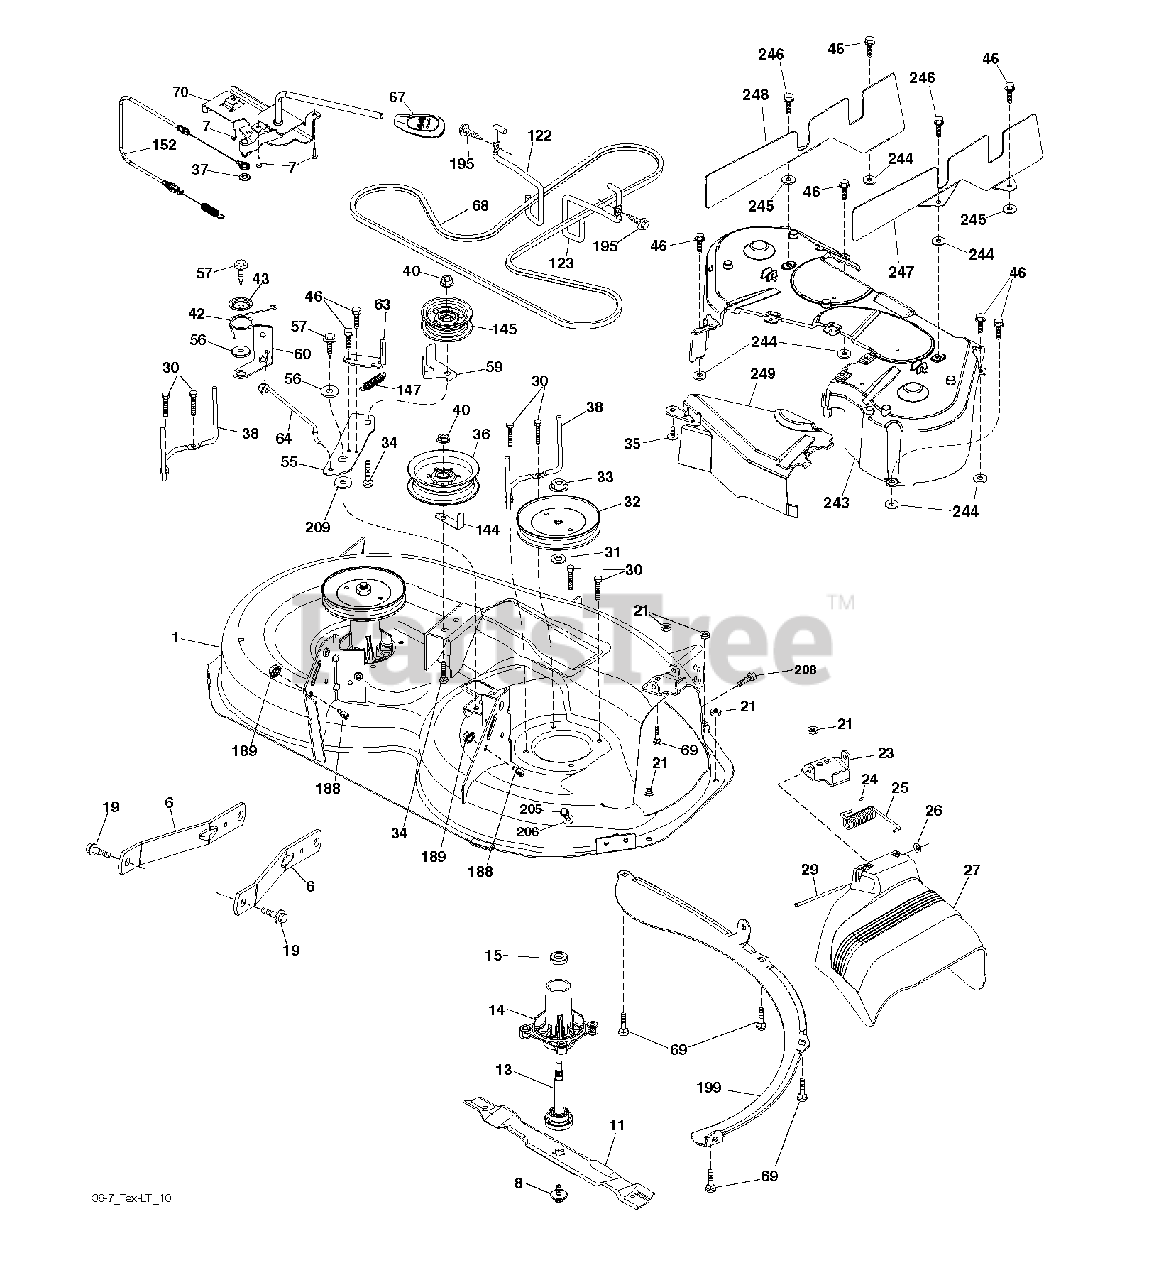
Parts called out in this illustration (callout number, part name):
6	ARM.SUSPENSION.MOWER.R
7	SCREW.#10 X 0.750.BOS THREAD
8	BOLT.WASHER.ASM.7/16-2
11	BLADE 38" PREMIUM
13	SHAFT.ASM.MDRL.N/GREASE.38
14	HOUSING MANDREL
19	BOLT.SHOULDER
21	LOCKNUT
23	BRKT.DEFLECTOR.38"2005+
24	CAP-SLEEVE LT
25	SPRING.TORSION.DEFLECT
26	NUT PUSH M
29	ROD.HINGE
30	SCREW, WASHER HEAD
31	WASHER.SPACER.MANDREL
32	PULLEY.MANDREL.5.0.PD.38"
33	NUT.FLANGE.LOCK.TOP
34	BOLT.3/8-16X1.50
35	FASTENER.XMAS.TREE
38	KEEPER BELT LH MANDREL
40	NUT LOCK FLG 3/8-16 UNC
42	SRPING.TORSION.RETAINE
43	SPRING.TORSION.BRAKE
46	SCREW.1/4-20X5/8
55	IDLER.ARM
56	SPACER.RETAINER
57	SCREW 3/8-16X1
59	GUARD, BELT
60	ARM BRAKE MOWER RH 38"
63	ARM BRAKE MOWER RH
64	LINK BRAKE
67	HANDLE.CLUTCH.CABLE.LT
69	BOLT
70	CLUTCH.ASM.MANUAL.LT.PRED
122	KEEPER BELT ENGINE LH
123	KEEPER BELT RH
144	KEEPER BELT
145	PULLEY.IDLER.48"PRIMARY
147	SPRING RETURN
152	CLUTCH CABLE
188	STUD.FASTNER.W/ANTI-ROTATE
189	NUT LOCK HEX FLANGE 5/16-18
195	SCREW, 3/8-16X3/4
199	BAFFLE VORTEX
205	SCREW
206	WASHER
208	SCREW 3/8-16X1/2
209	WASHER 12/32X2X10GA
244	PALNUT 1/4
246	SCREW, 5/16-18 X 1/2
